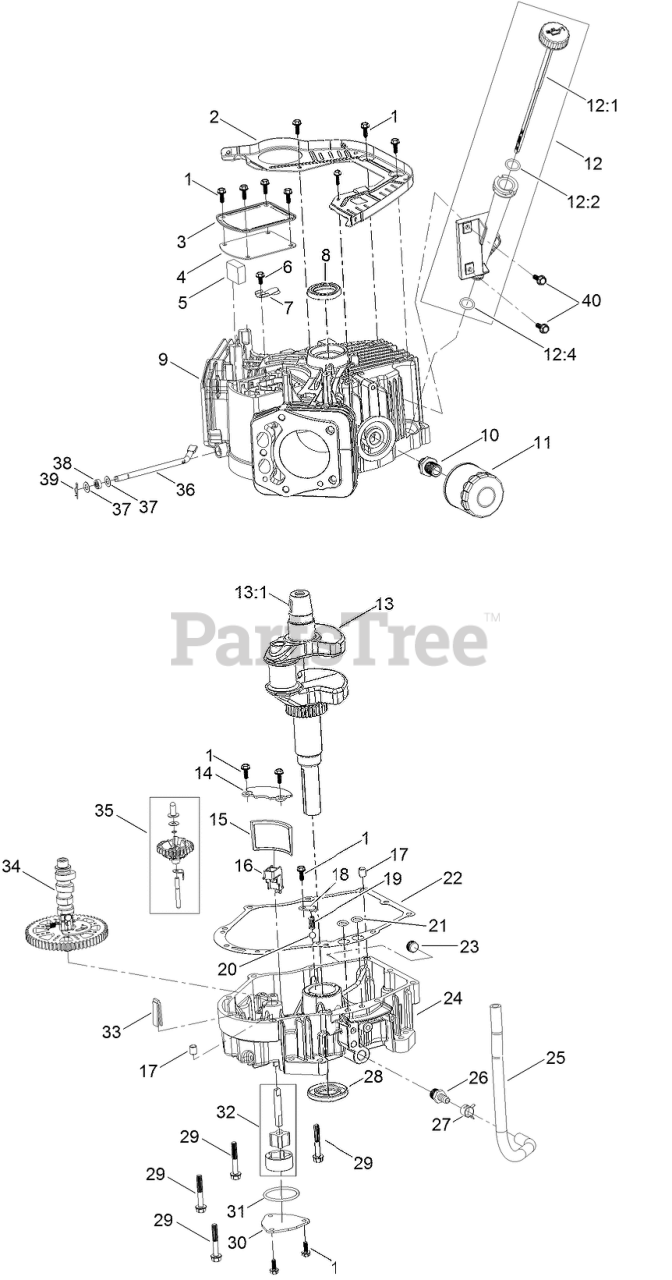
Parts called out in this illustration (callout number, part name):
1	SCREW-HHF
2	BAFFLE
3	COVER-BREATHER
4	GASKET-BREATHER
5	FILTER-BREATHER
6	SCREW-HHF
7	VALVE-BREATHER
8	SEAL-OIL
9	CRANKCASE
10	FITTING-THREADED, OIL FILTER
11	FILTER-OIL
12	OIL TUBE ASM
12:1	DIPSTICK
12:2	O-RING
12:4	O-RING
13	CRANKSHAFT
13:1	KEY-WOODRUFF
14	COVER-SCREEN, OIL
15	SCREEN-OIL
16	RETAINER-SCREEN
17	PIN-DOWEL
18	PLATE-RETAINER
19	SPRING
20	VALVE-BALL
21	O-RING
22	GASKET-COVER, CRANKCASE
23	PLUG-DRAIN
24	COVER-CRANKCASE
25	OIL DRAIN HOSE ASM
26	FITTING-HOSE
27	CLAMP-HOSE
29	SCREW-HHF
30	COVER-OIL PUMP
31	O-RING
32	OIL PUMP ASM
33	DEFLECTOR-OIL, RUBBER
34	CAMSHAFT
35	GOVERNOR ASM
36	ROD-GOVERNOR
37	WASHER-PLAIN
38	SEAL-OIL
39	PIN-HAIR
40	SCREW-HHF
